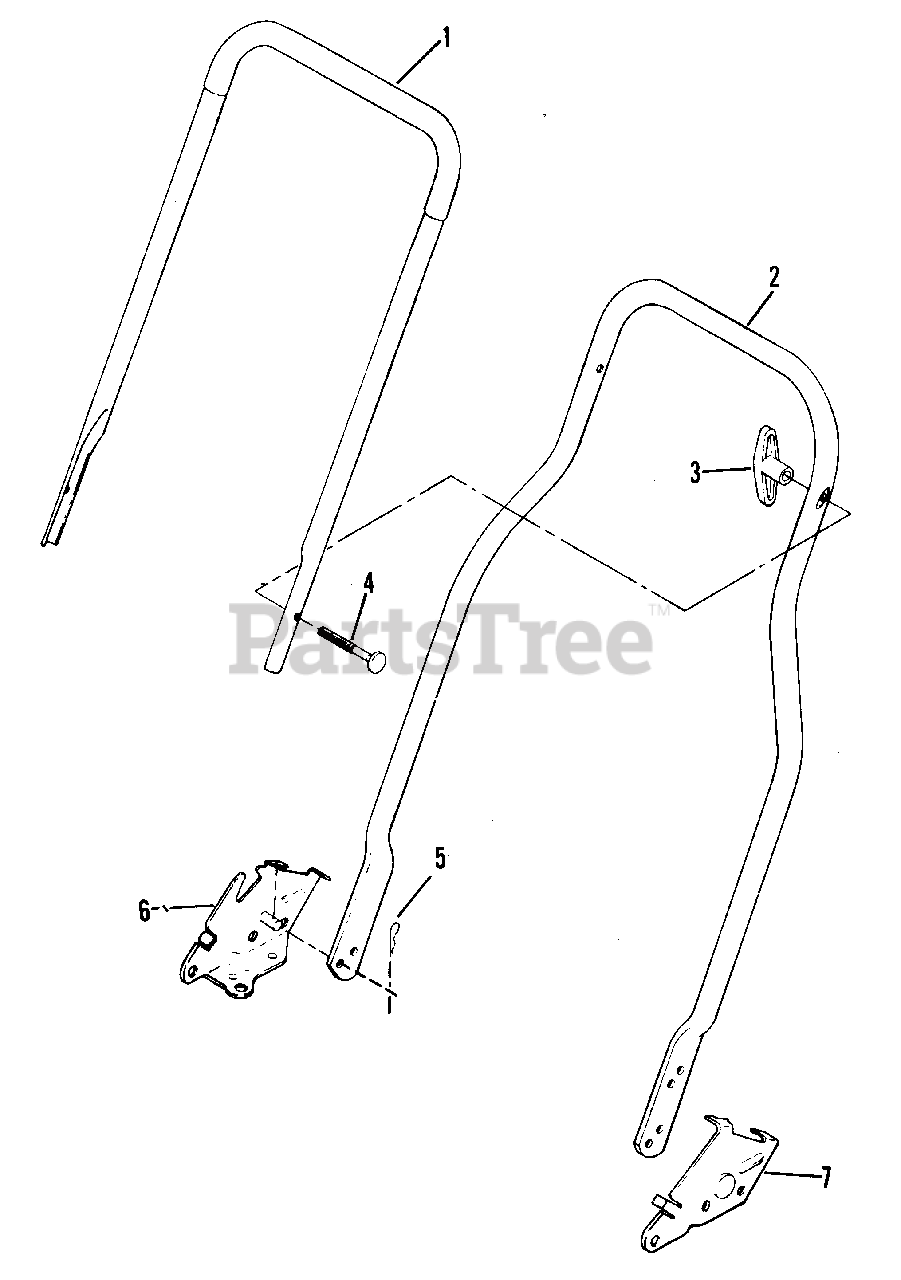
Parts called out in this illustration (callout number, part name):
1	Top Handle & Grip Assembly
2	Handle Section-Bottom
3	Knob
4	Screw
5	Hair Pin
6	Handle Bracket-R.H.
7	Handle Bracket-L.H.
